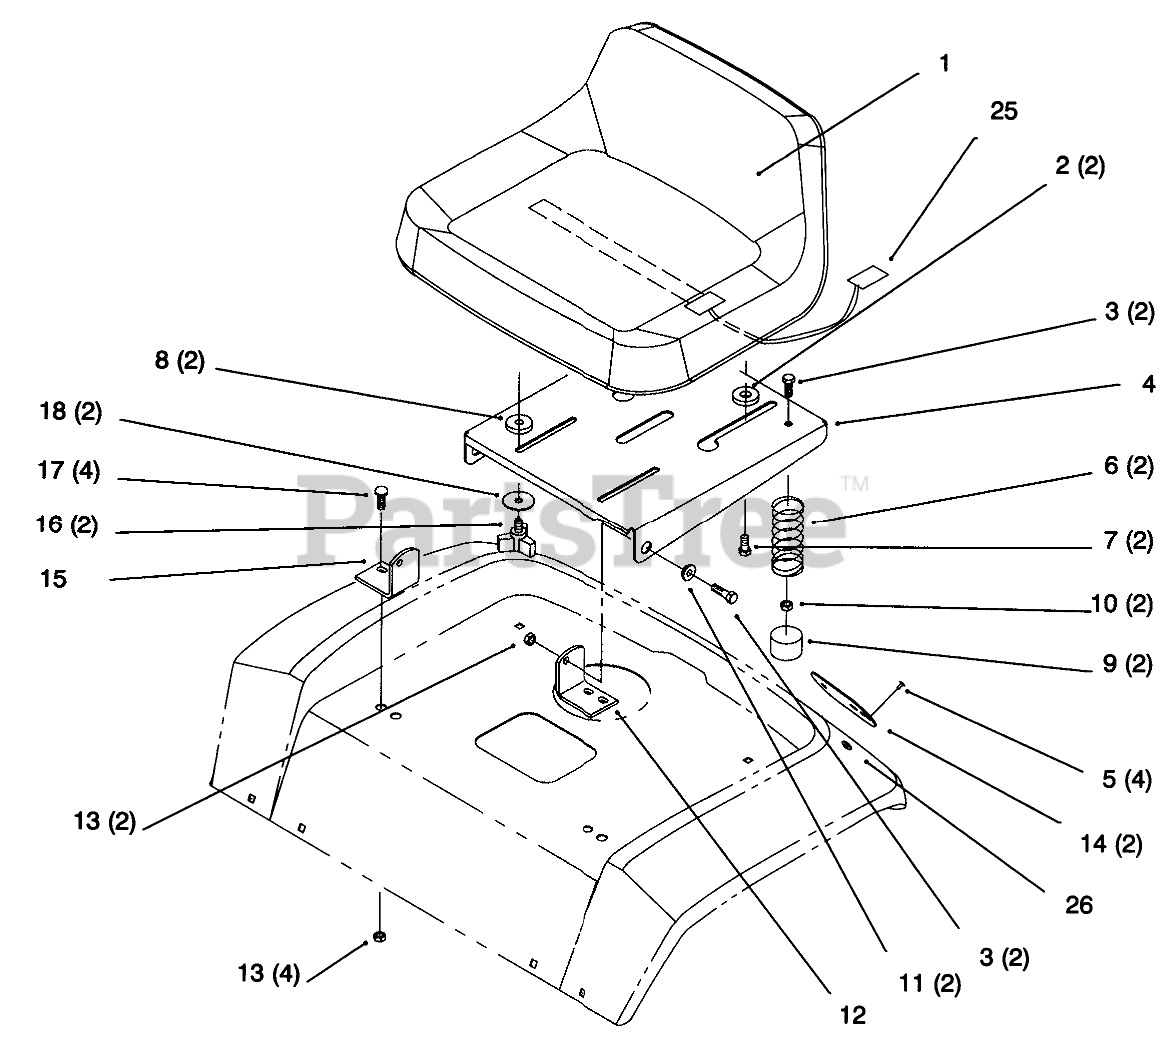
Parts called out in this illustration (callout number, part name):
1	Seat (Only On: 72042, 72043)
1	Seat (Only On: 72062, 72063, 72103)
2	SPACER-NYLON
3	SCREW-HH
4	SUPPORT - SEAT (BLACK)
5	RIVET-BLIND
6	SPRING-COMPRESSION
7	BOLT-SHOULDER
8	SPACER-NYLON
9	CAP-PROTECTOR
10	NUT-LOCK, NI
11	BUSHING
12	BRACKET-PIVOT, LH
13	NUT-LOCK, NI
14	REFLECTOR-STICK ON
15	BRACKET-PIVOT, RH
17	BOLT-CARR
18	WASHER-PIVOT
25	SWITCH-SEAT
26	WASHER-PLAIN
